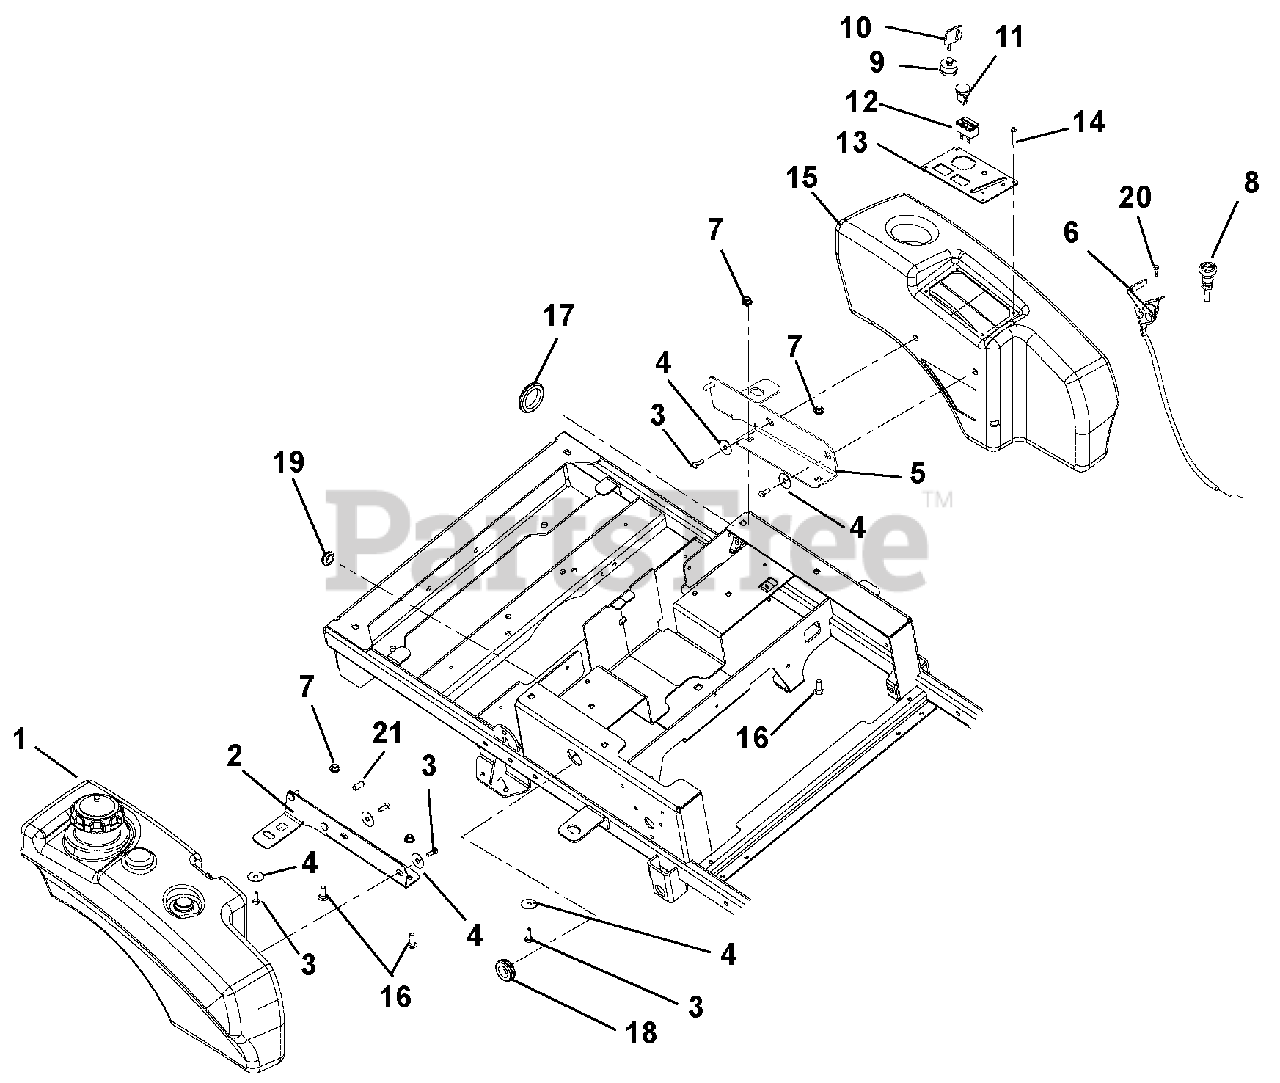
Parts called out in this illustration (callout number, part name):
1	Tank, XL
2	Weldment, RH Tank Mount
3	Bolt, Serrated Hex Flange Washer Head .312-18 x .50
4	Washer, Flat Steel .347 x 1.254 x .048
5	Weldment, LH Fender Mount
6	Cable, Throttle
7	Nut, .38-16 Nyloc Flange
8	Cable, Choke
9	Key Switch
10	Key, w/cap
11	Switch, Clutch
12	Hour Meter, Digital
13	Panel, Control
14	Rivet, Plastic .195 Diameter
15	Fender, XL
16	Bolt, Round Head Square Neck .38-16 x 1.00 Grade 5
17	Grommet, 2.00"
18	Grommet .125 x 1.000 ID
19	Grommet, Rubber 5/8 ID/1.13 OD
20	Screw, Tapping 10-24 x .50 Hex Washer Head Thread
21	Cap, End .312 x 1.00
